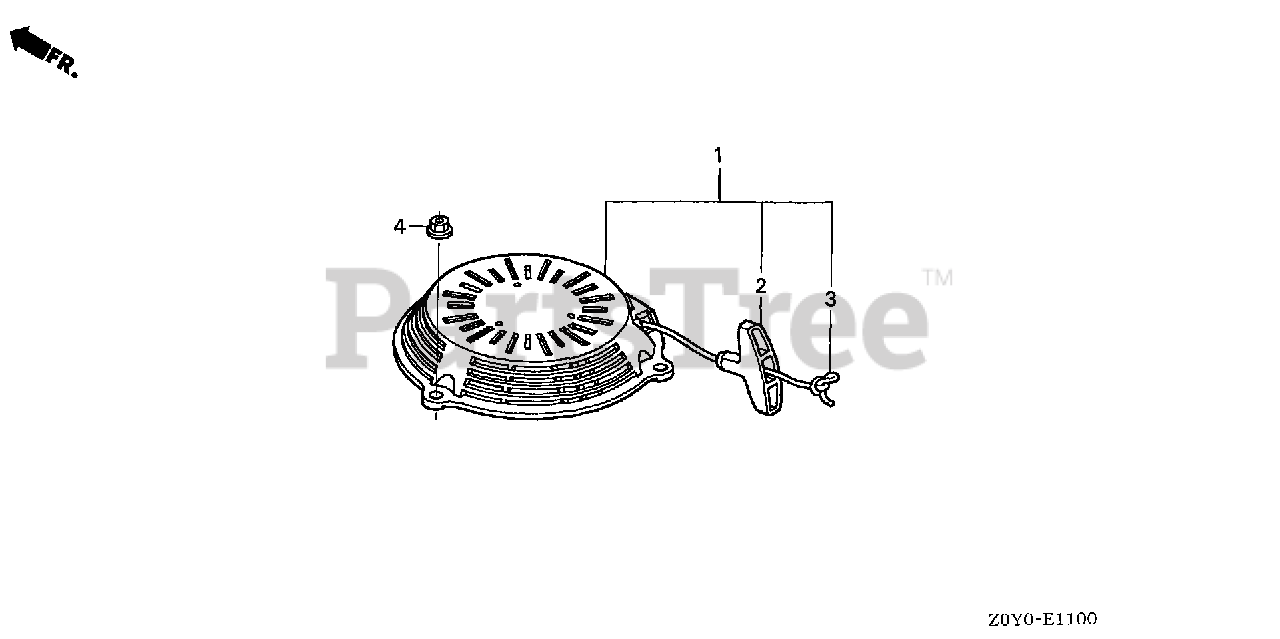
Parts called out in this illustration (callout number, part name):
1	STARTER ASSY., RECOIL *R280* (POWER RED)
1	STARTER ASSY., RECOIL *NH1* (BLACK)
1	STARTER ASSY., RECOIL *YR288R* (WOLF ORANGE)
2	GRIP, STARTER
3	ROPE, RECOIL STARTER (LONG TYPE)
4	NUT, FLANGE (6MM)
